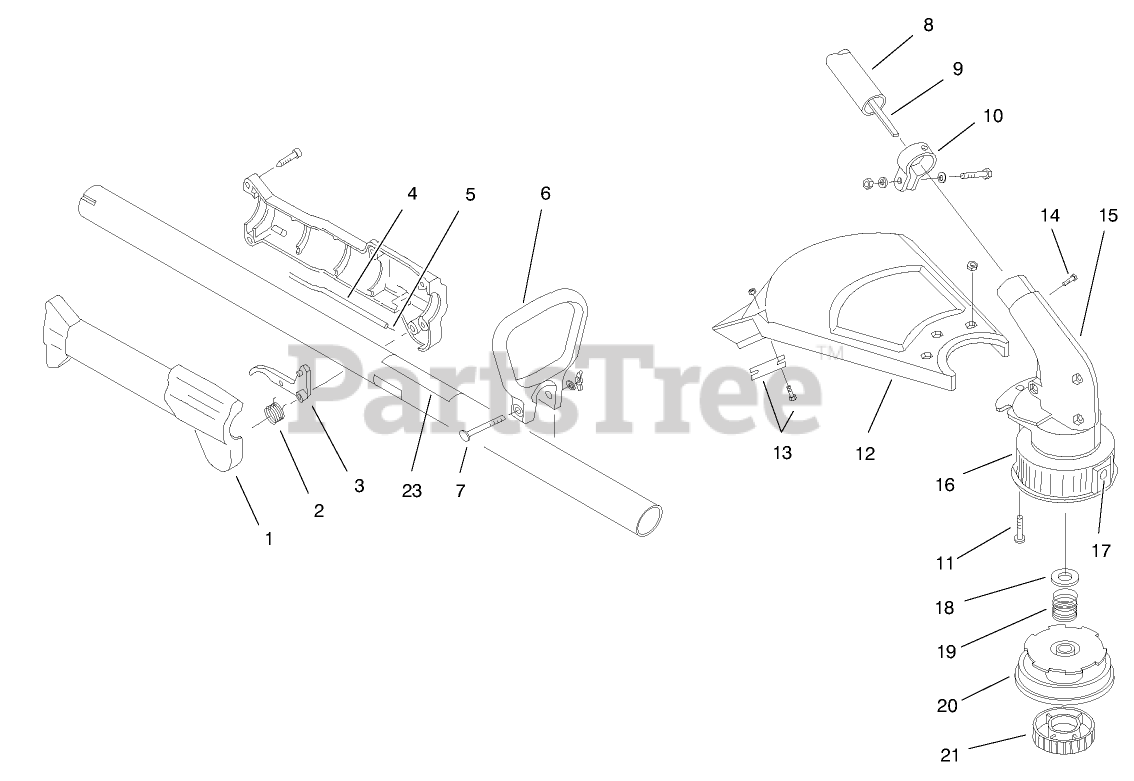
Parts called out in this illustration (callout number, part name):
1	Throttle Housing & Trigger Asm.
2	THROTTLE TRIGGER SPRING
3	TRIGGER - THROTTLE
4	HOUSING-CABLE
5	THROTTLE CABLE WIRE
6	D-HANDLE
7	HARDWARE - D-HANDLE
8	ASM - SHAFT HOUSING
9	Drive Shaft
10	CLAMP ASM - UPPER
11	ASM - GUARD MTG SCREW
12	Guard and Blade Asm.
13	BLADE ASM
14	ANTI-ROTATION SCREW
15	ASM - GEAR BOX
16	OUTER SPOOL EYELET ASM
17	EYELET
18	RETAINER WASHER(SET OF 10)
19	SPRING
20	REEL - INNER
21	Assy.-Bump Head
23	Decal-Safety Symbol
